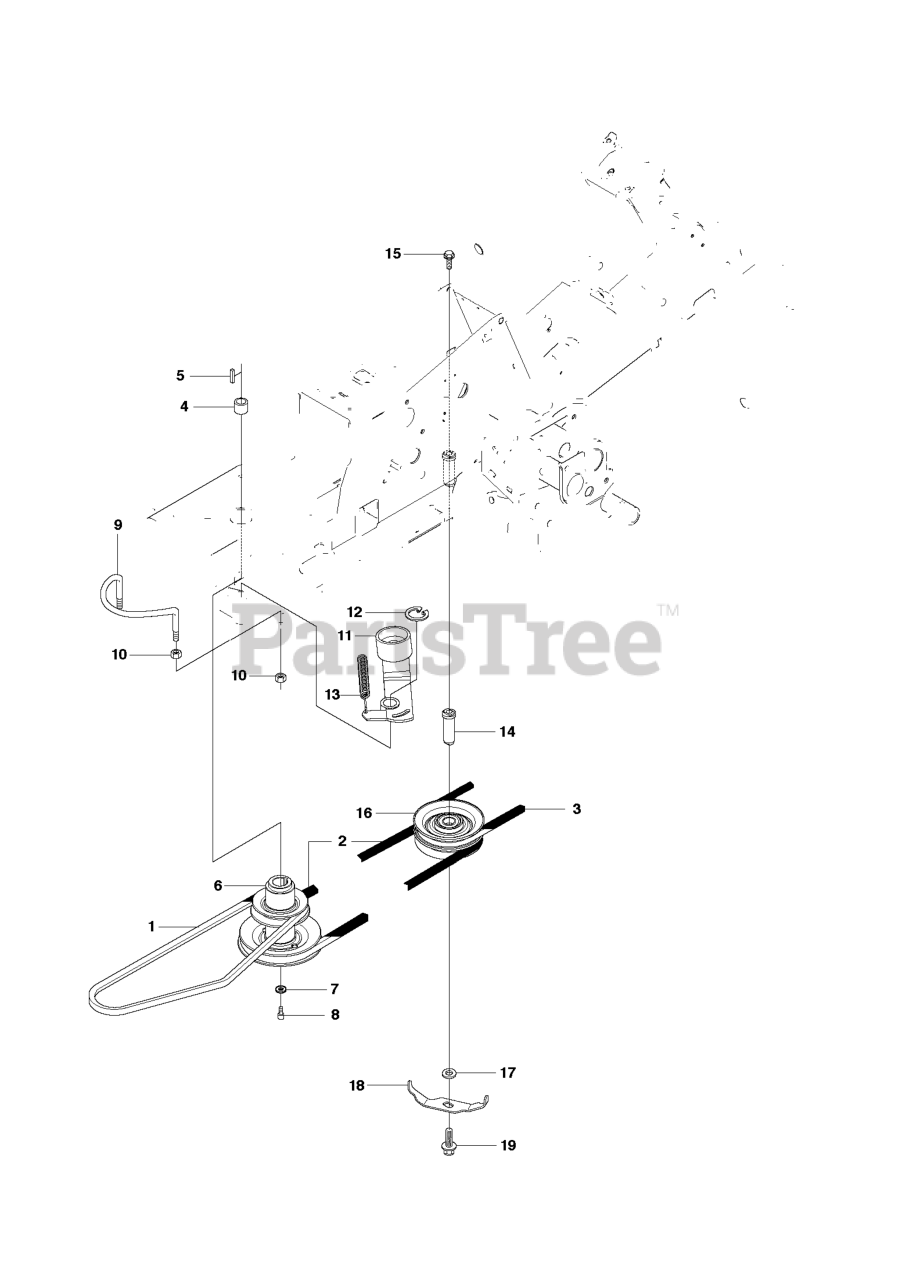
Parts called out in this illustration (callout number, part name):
9	BELT GUIDE
10	NUT
12	RETAINING RING SGA 25
14	SHAFT
18	BELT GUIDE
19	BOLT
